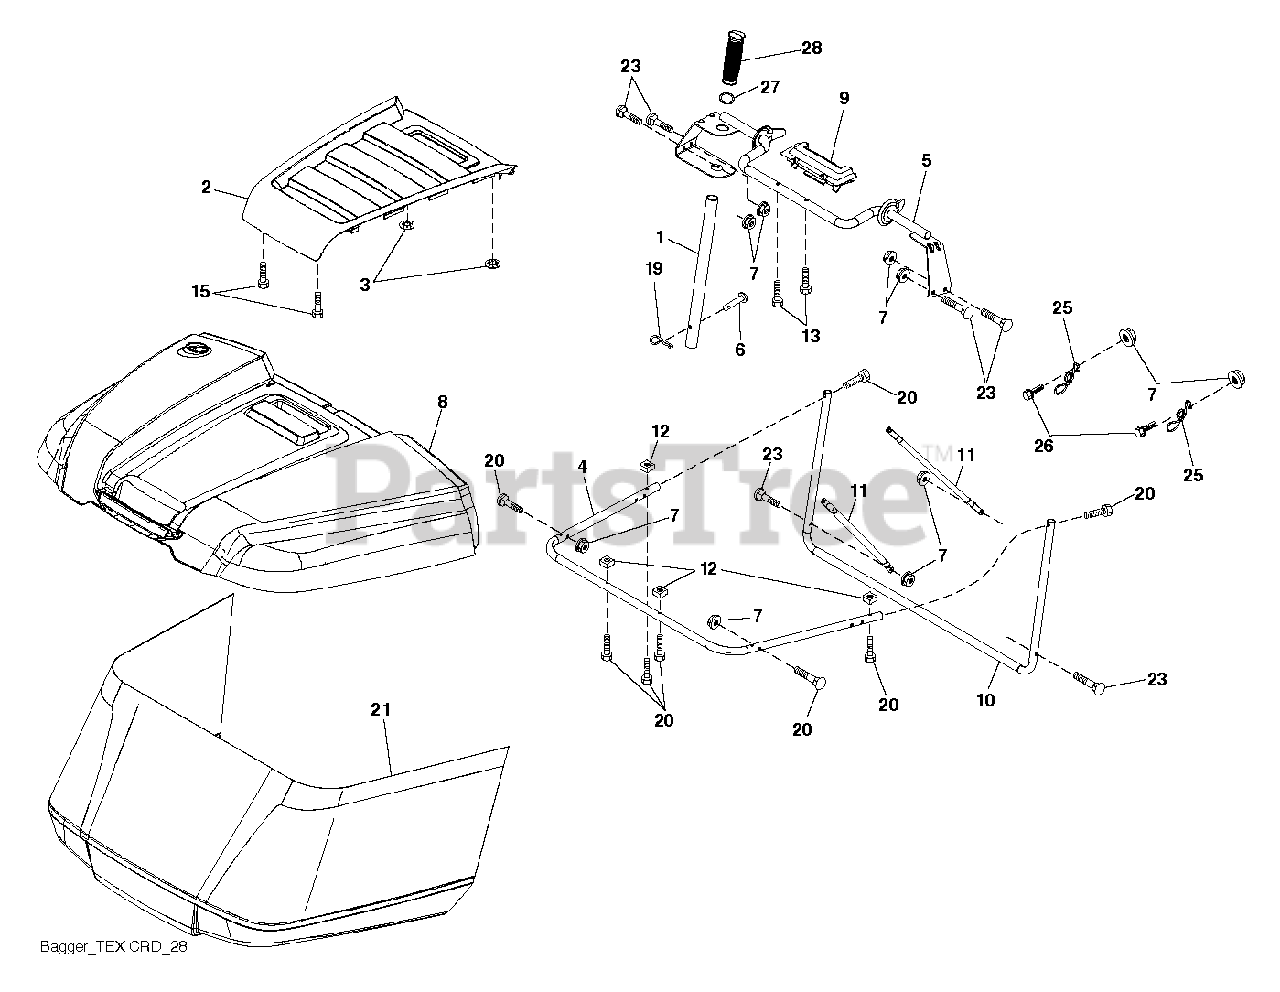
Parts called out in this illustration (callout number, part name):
1	TUBE.HANDLE.BAGGER.CRD/SRD.BLA
2	APPLIQUE.TOP.BAG.SRD.ORANGE
3	NUT.PUSH.156
4	SUBASM.TOP.TUBE.TEX.CRD
5	FRAME.ASM.TOP.BAGGER.SRD
6	RIVET,DRILLED
7	NUT T
8	BAGGER.TOP.SRD.APPLIQUE
9	INSERT.HANDLE.BAGGER.(2 2)
10	FRAME FRAME.FRONT.TEX.CRD
11	BRACE BRACE SIDE TUBE
12	NUT.SQUARE.1/4
13	SCREW.1/4X1.150.HXWSH
15	SCREW,#8.FLAT.HEAD.DRILL.TIP
19	PIN.COTTER.5/16.BOW TI
20	SCREW.HEXCAP.1/4-20X1.375(2 2)
21	BAG SUBASM. TEX CRD GEN 2 HUSQ
25	SPRING.LATCH.BAGGER.SRD
26	SCREW HEX CRT
27	RB GROMMET.RUBBER.SRD
28	GRIP.HANDLE.BLACK
